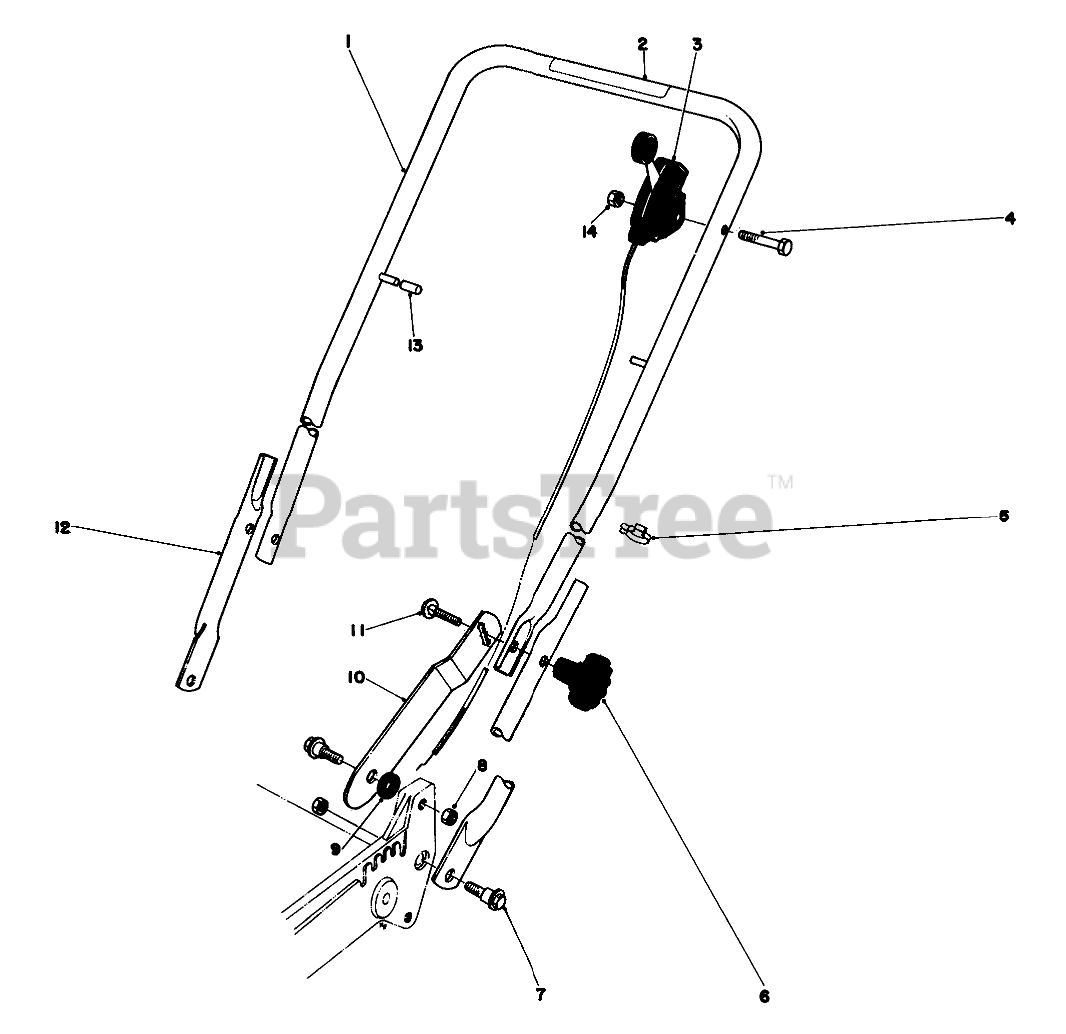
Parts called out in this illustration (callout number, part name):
1	Upper Handle
2	Decal
3	Throttle Control
4	SCREW-HH
5	BOWDEN CLIP
7	Screw
8	Nut
9	SPACER
10	Handle Latch L.H.
11	SCREW-CARR
12	LOWER HANDLE
13	CAP-VINYL
14	NUT-LOCK
